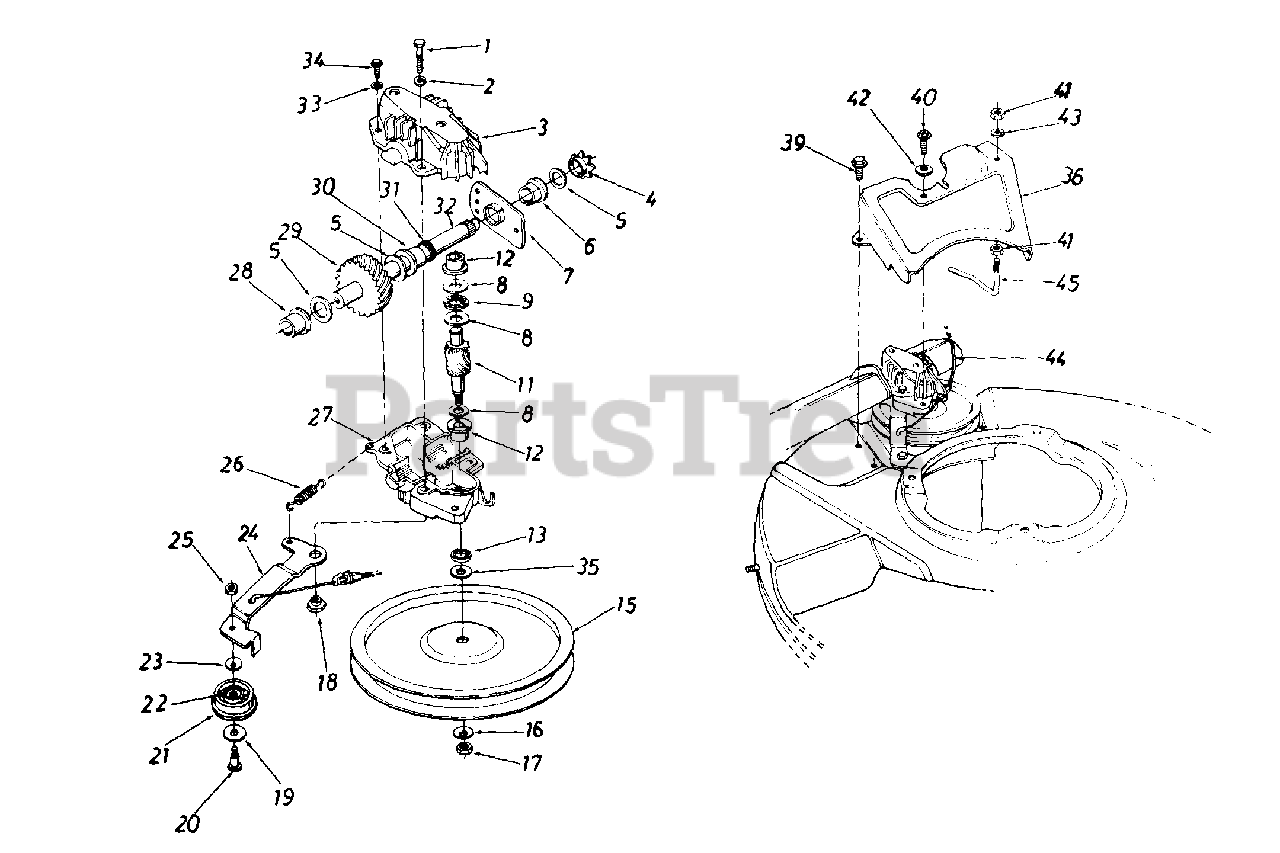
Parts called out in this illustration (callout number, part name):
1	Hex Bolt w/Patch 1/4-20 x 1.25"
2	L-Wash. 1/4" I.D.
3	Upper Hsg. Half
4	#48 Sprocket 7 Tooth x 1/2 Pitch
5	Fl-Wash. 5/8" I.D. x .030
6	Hex Flange Brg..631" I.D.
8	Thrust Wash..382" I.D. x .70" O.D.
9	Thrust Bearing .375" I.D. x .812" O.D.
11	11 Tooth Helical Gear
12	Flange Bearing
13	Oil Seal
15	Fl-Pulley 5.06" I.D.
16	Bell-Wash..265" I.D. x .75"
17	Hex Nut 1/4-28 L.H. Thd.
18	Shld. Spacer .375" Dia. x .170
19	Fl-Wash..390" I.D. x 1.0"
20	Shld. Bolt .375" Dia. x .40"
21	Fl-Idler Plastic 1.50" Dia.
22	Needle Brg. .375" x .31"
23	Bell-Wash..265" I.D. x .75"
24	Idler Brk't. Ass'y.
25	Hex Patch L-Nut 1/4-28 Thd.
26	Extension Spring 1.12" Lg.
27	Lower Hsg. Half
28	Flange Bearing .56 Dia.
29	33 Tooth Helical Gear
30	Flange Bearing .629 Dia.
31	Oil Seal .625 Dia,
32	Gear Sprocket Shaft
33	L-Wash. #10 I.D.
34	Hex B-Tap Scr. #10 x .62"
35	Hex Washer .26" x .88"
40	Hex B-Tap Scr. 1/4 x .62" Lg.
41	Hex Nut 1/4-20 Thd.
42	Bell-Wash..265" I.D. x .75"
43	L-Wash. 1/4" I.D.
44	S.P. Cable - 48" Lg.
45	S.P. Belt Guards
